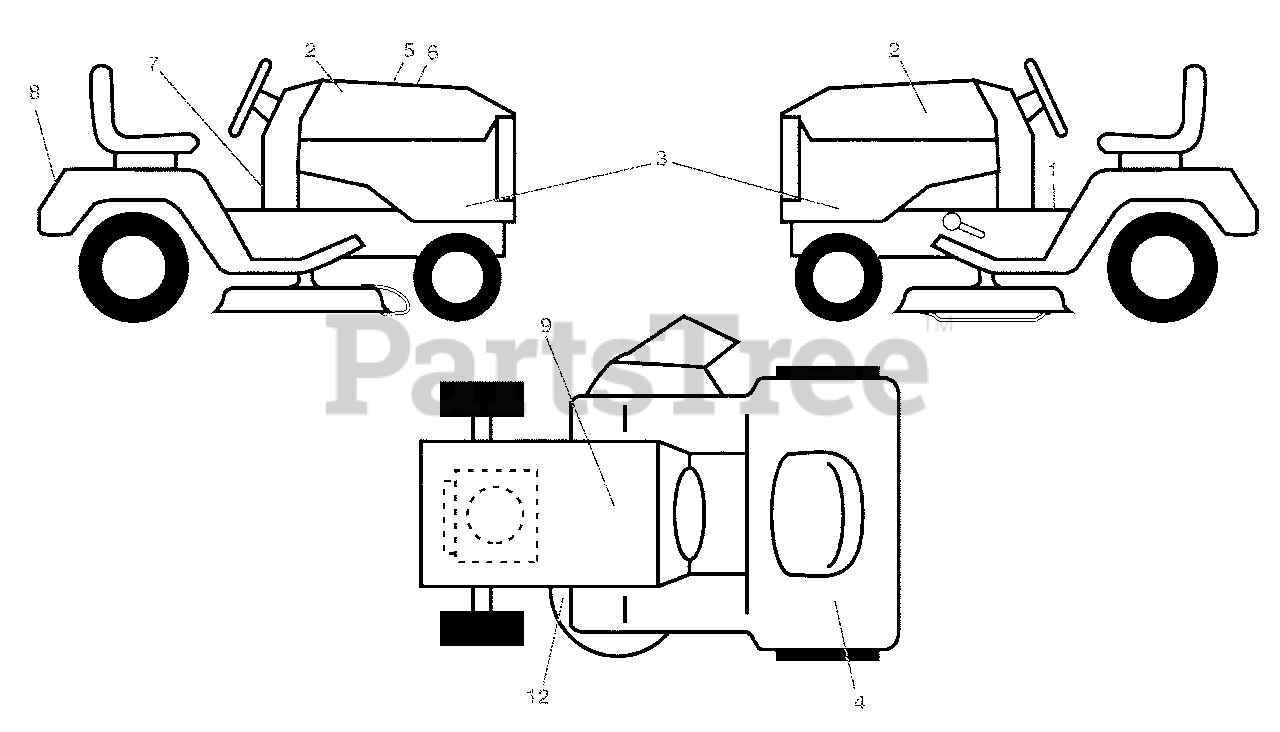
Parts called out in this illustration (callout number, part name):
1	Decal, Fender Warning
2	Decal, Hood
3	Decal, Hood Panel SD
4	Decal, Ethanol E85
5	Decal, Customer Respons.
6	Decal, Replacement
7	Decal, Warning Spark Arrester
8	Decal, Fender
9	Decal, Battery Dnge/Poi
12	Decal, Mower V-Belt Schematic
